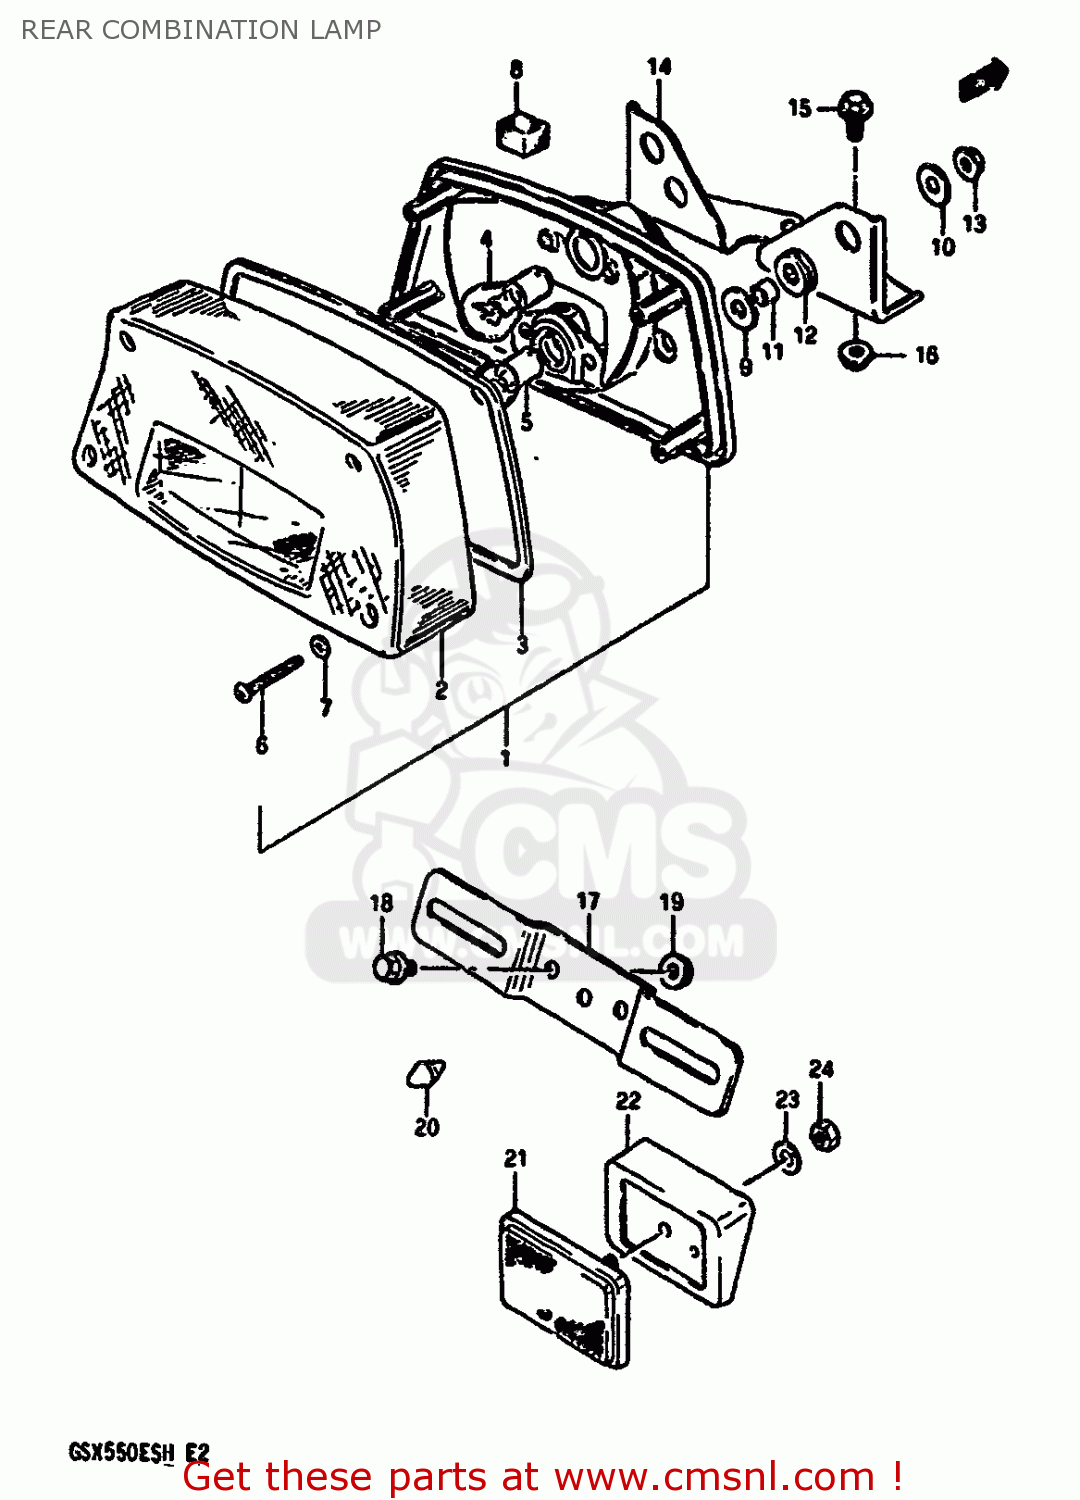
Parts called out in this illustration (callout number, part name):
1	LAMP ASSY,REAR COMBINATION
2	LENS
3	GASKET
4	BULB(12V21/5W)
5	BULB
7	GASKET (NAS)
8	CUSHION,REAR COMBINATION LAMP
9	WASHER
10	WASHER(6,5X22X1.6)
11	SPACER
12	CUSHION,RR COMBINATION
13	NUT
14	BRACKET,REAR COMBINATION LAMP
15	BOLT
16	NUT
17	PLATE,RR LICENSE
18	BOLT 6X12
19	NUT
20	CUSHION
21	REFLEX REFLECTOR,RR
22	SPACER
23	WASHER(5.2X16X1)
24	NUT
